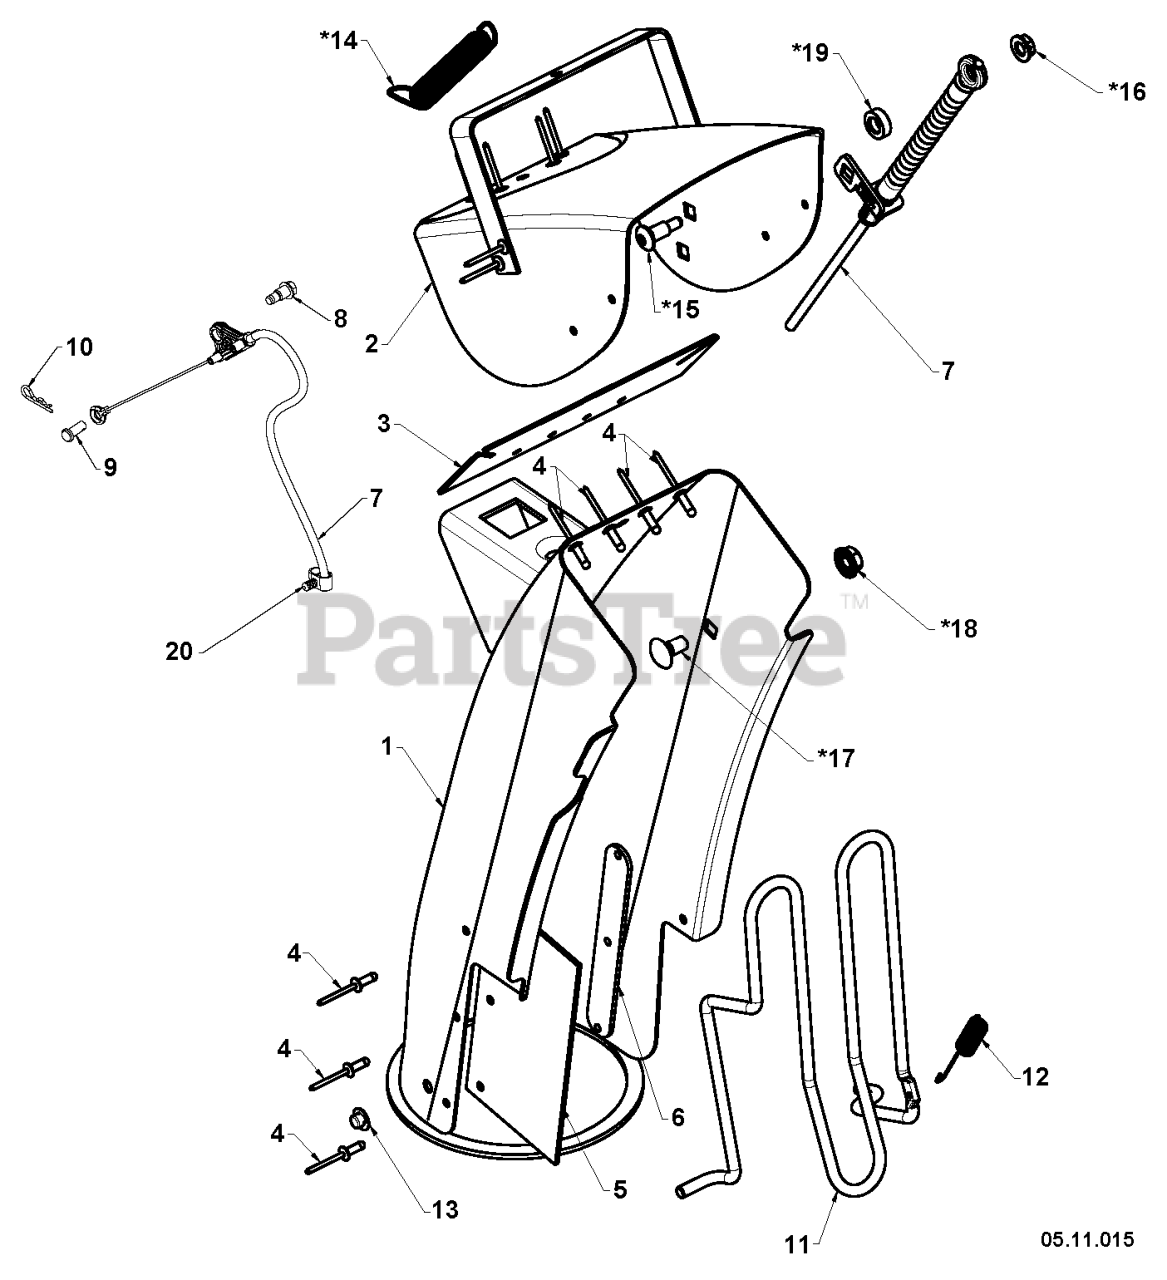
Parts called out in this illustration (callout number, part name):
1	ASM.CHUTE/DEFLECTOR.668
8	BOLT SHOULDER_1/4-20_TRILOB
9	PIN CLEVIS .25 X ..4375
10	HAIRPIN.SOFT.ZINC.059X1.125
11	GUARD ROD CHUTE GUARD SHORT CL
12	SPRING.CHUTE.GUARD
13	NUT
20	CLIP.ROUTING DUAL
